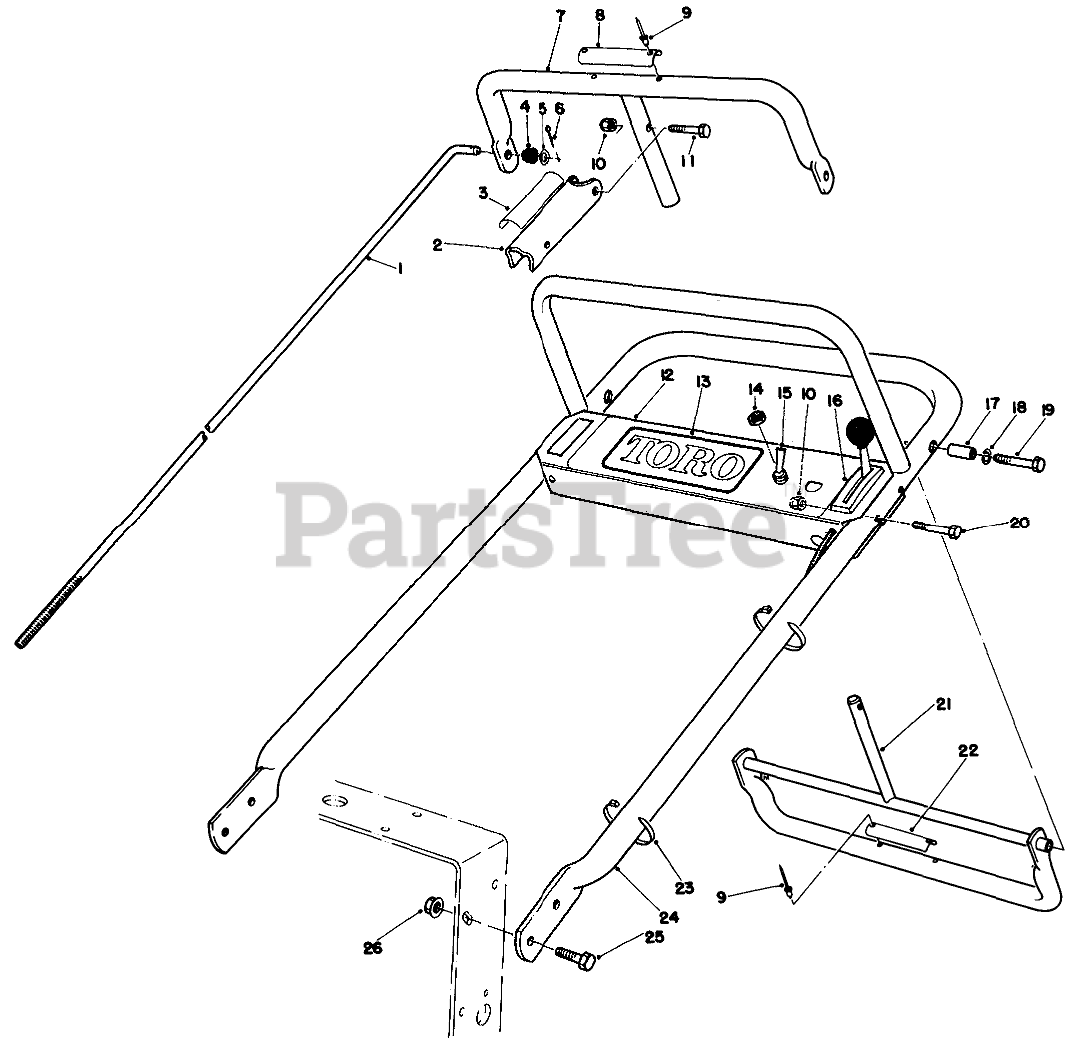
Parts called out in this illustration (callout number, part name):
1	ROD-CONTROL
2	Lever-Parking Brake
3	DECAL-LEVER, PARKING
4	GROMMET-RUBBER
5	WASHER-PLAIN
6	PIN-COTTER
7	Bar-Control
8	DECAL-CONTROL BAR
9	RIVET-BLIND
10	NUT-LOCK, NI
11	SCREW-SHH
12	Panel-Control
13	PANEL DECAL
14	NUT
15	Switch
16	THROTTLE-CONTROL
17	PIVOT-SPACER
18	WASHER-LOCK
19	SCREW-HH
20	SCREW-SHH
21	Control-Pivot
22	DECAL-REVERSE HANDLE
23	TIE-CABLE
24	HANDLE-UPPER
25	SCREW-HHF
26	NUT-HF
